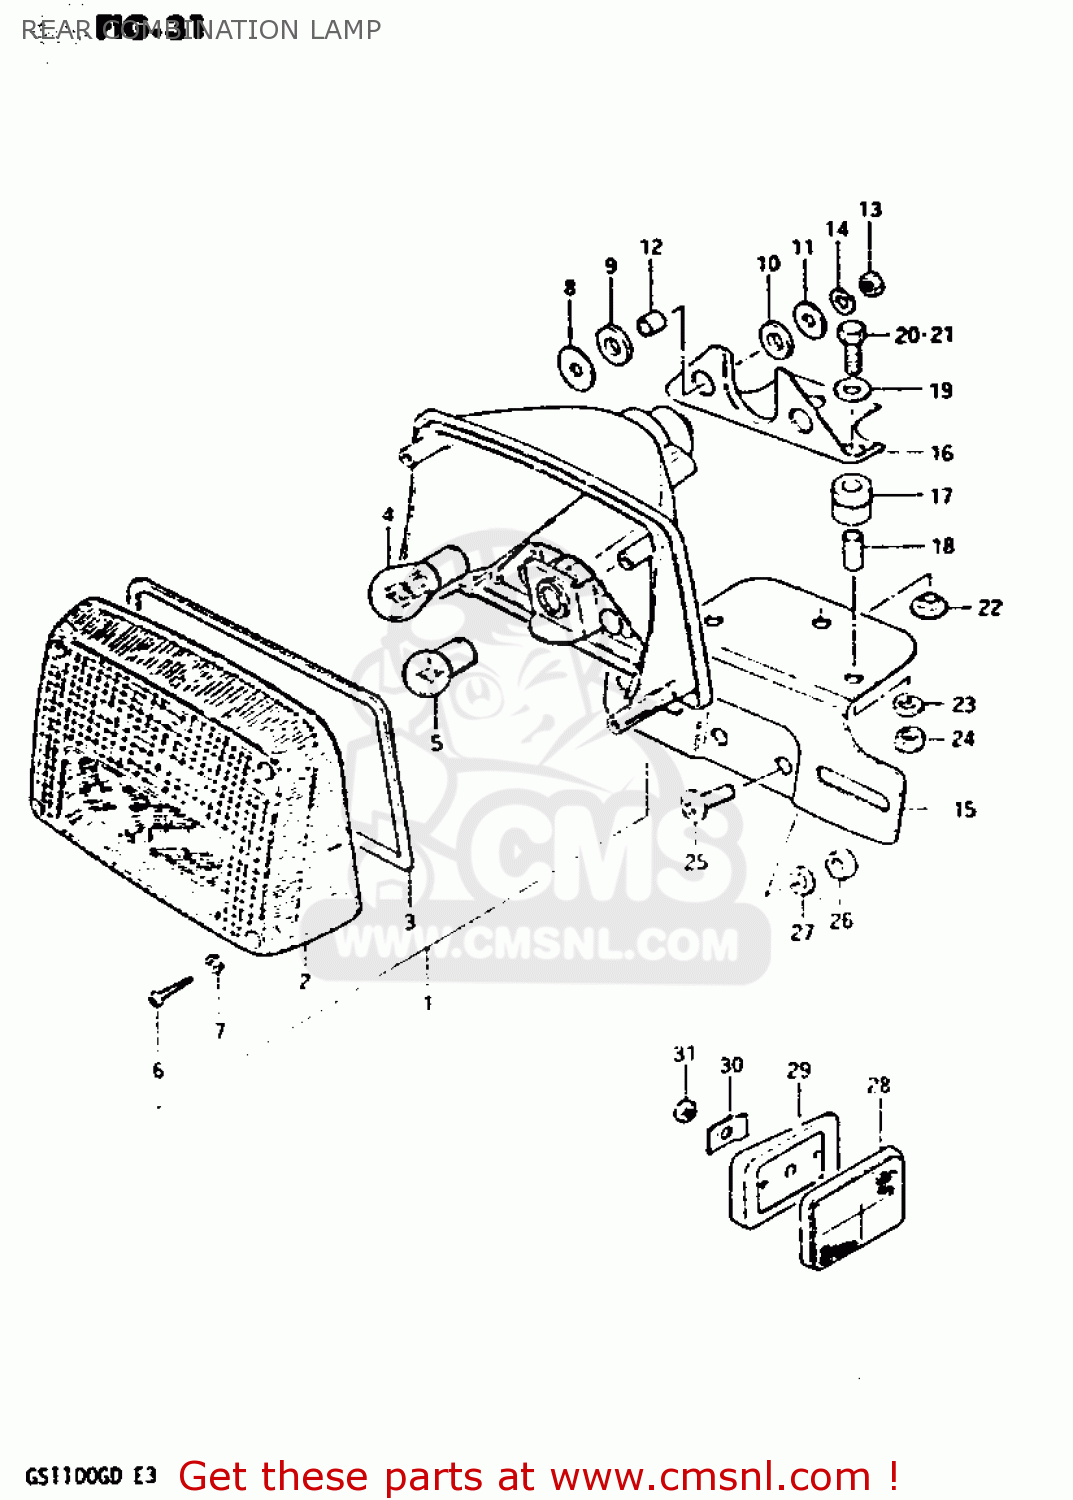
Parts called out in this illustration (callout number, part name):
1	LAMP ASSEMBLY,REAR COMBINATION
2	LENS
3	GASKET (NAS)
4	BULB(12V23W)
5	BULB(12V8W)
6	SCREW,REAR COMBINATION LAMP
7	GASKET (NAS)
8	WASHER
9	CUSHION
10	CUSHION
11	WASHER(6,5X22X1.6)
12	SPACER(6.1X9X7.5)
13	NUT
14	WASHER,LOCK
15	PLATE,REAR LICENSE
16	BRACKET,LICENSE PLATE
17	CUSHION, BRACKET
18	SPACER (6.4X9X15.5)
19	WASHER
20	BOLT
21	BOLT
22	WASHER
23	WASHER,LOCK
24	NUT
25	SCREW
26	NUT
27	WASHER,LOCK
28	REFLECTOR,REFLEX
29	SPACER
30	WASHER
31	NUT
